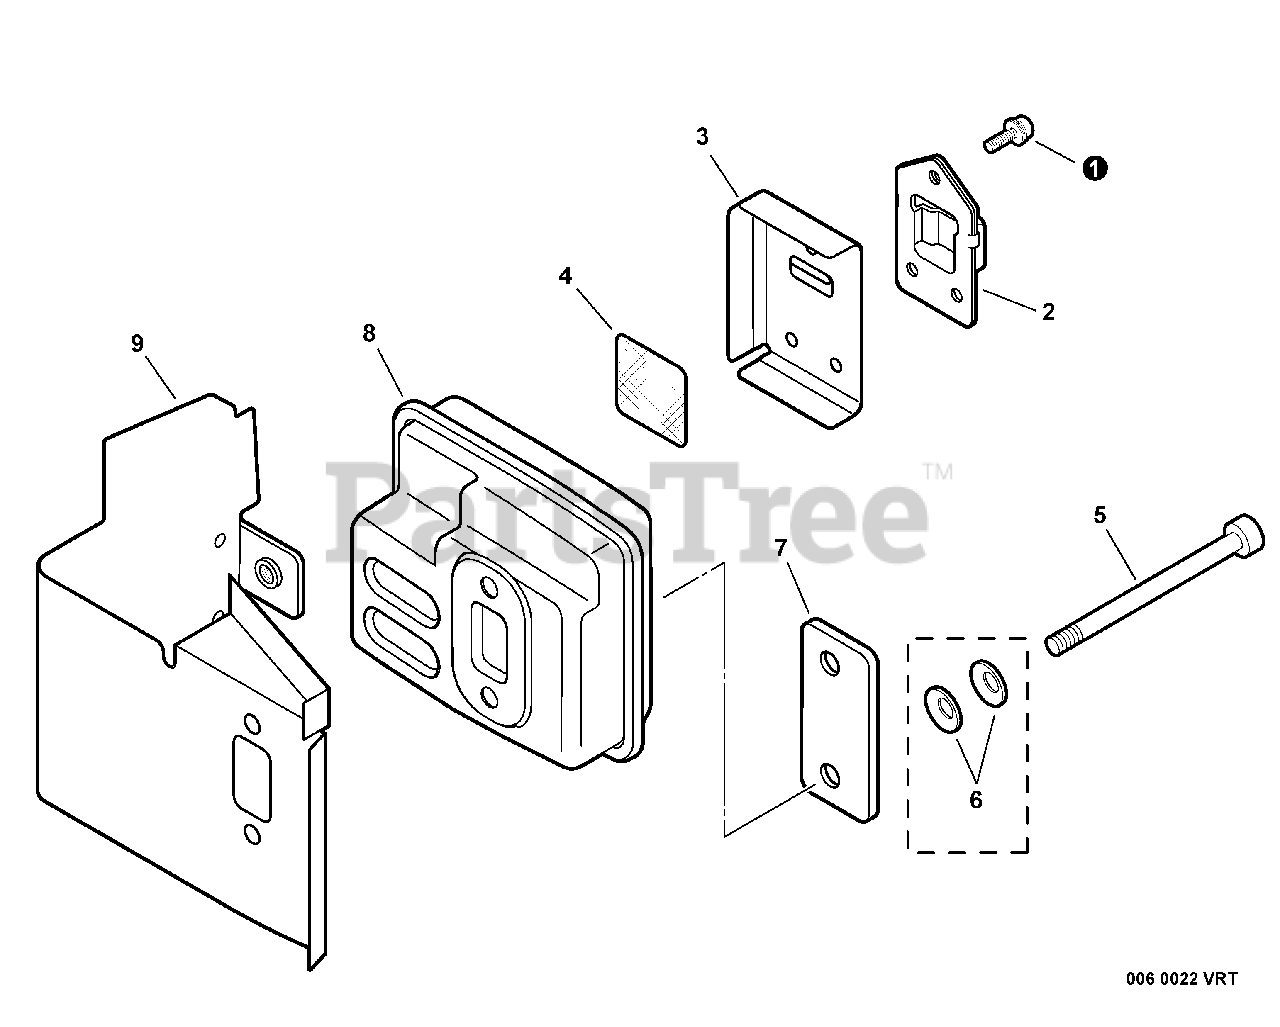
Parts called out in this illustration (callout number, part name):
1	SCREW 4×12
2	GUIDE, EXHAUST
3	GASKET, EXHAUST
4	SCREEN, SPARK ARRESTER
5	BOLT 5×55
6	CONICAL WASHER
7	PLATE, EYE
8	MUFFLER
9	HEAT SHIELD, EXHAUST
